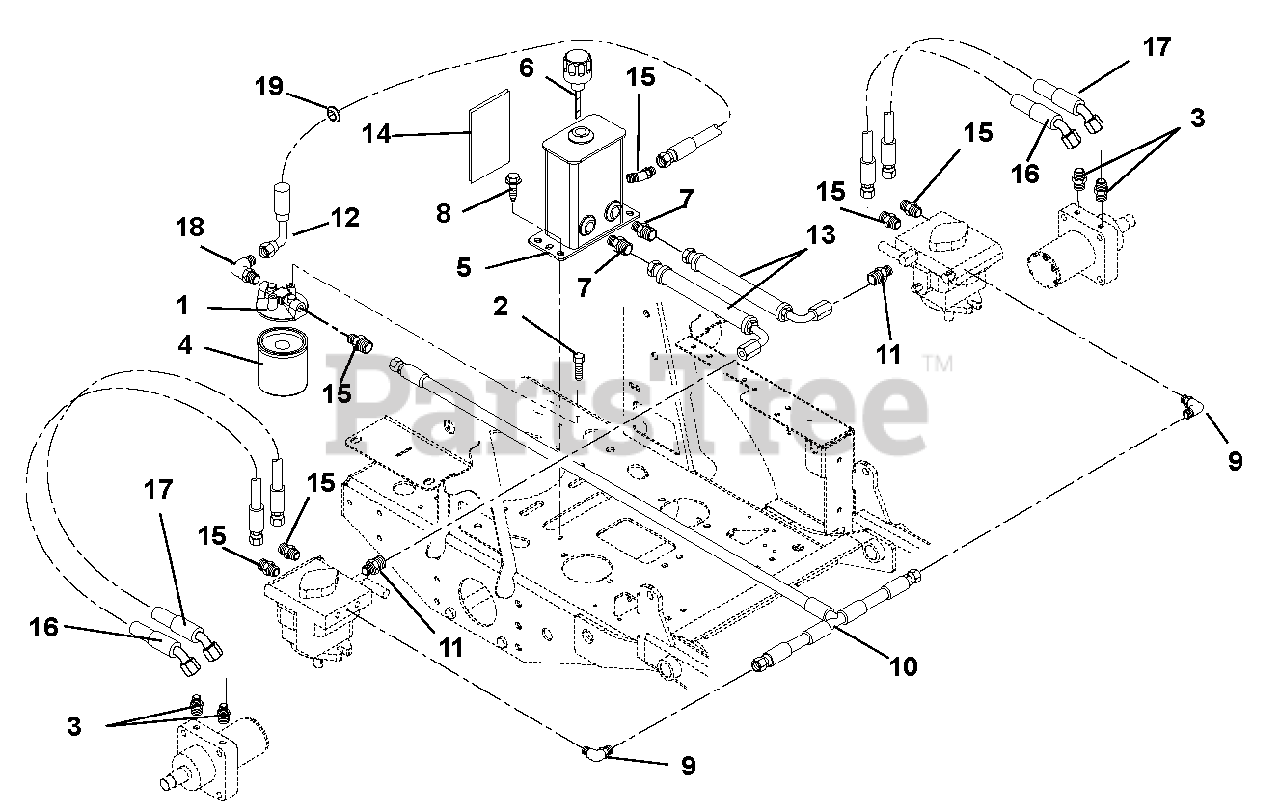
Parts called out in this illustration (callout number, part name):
1	Head, Filter
2	Bolt, Hex .25-20 x .50
3	Adapter, Hydraulic
4	Oil Filter
5	Weldment, Formed Hydraulic Tank – 3 Port
6	Breather Dipstick
7	Fitting, Hydraulic Straight M8O-M4F
8	Screw, Tapping .38-16 x .50 Hex Washer Head
9	Adapter, Hydraulic 8MB-12FPX90
10	Hose, Hydraulic .50 to .38 Tee Assembly
11	Fitting, Hydraulic (4-6 F5OLO)
12	Hose, Hydraulic .50-11-OK F8F0-F8F9
13	Hose, Hydraulic
14	Shield, Heat 5.50 x 4.50
15	Adapter, Face Seal 8 x 8 1/2 O-Ring 8 F5OLO, Steel
16	Hose, Hydraulic .50-11-3K
17	Hose, Hydraulic .50-12-3K
18	Fitting, Hydraulic EL M8F-M80
19	Grommet, 1.25 ID x 1.50 OD
